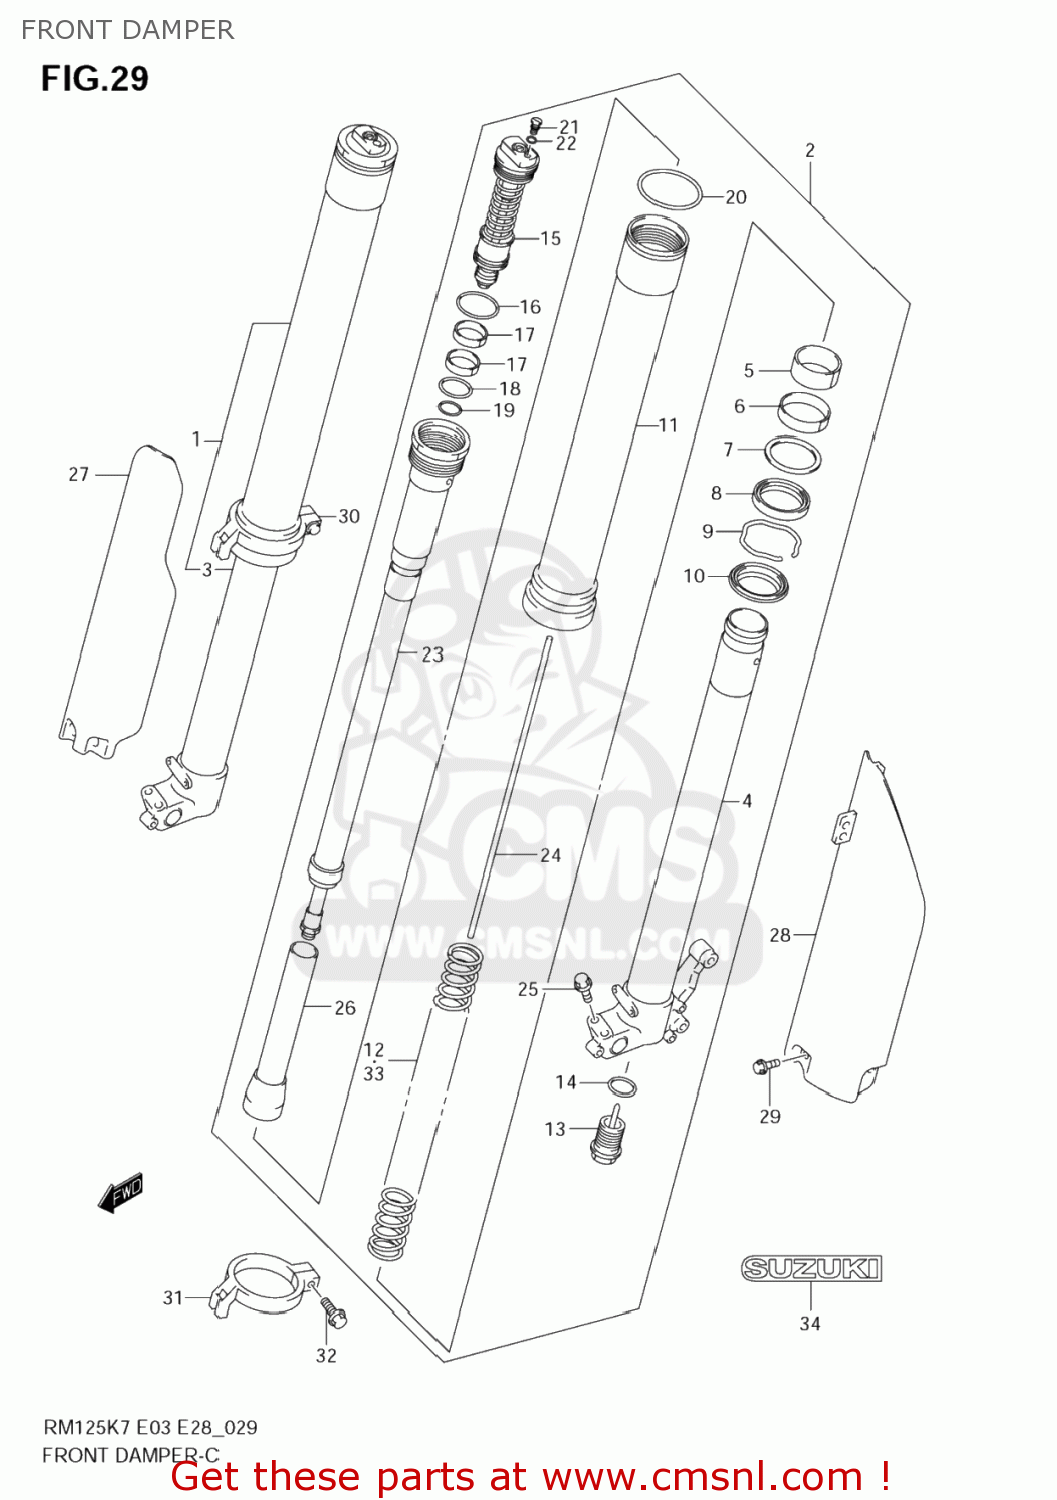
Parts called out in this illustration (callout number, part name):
1	DAMPER ASSY,FR FORK,R
2	DAMPER ASSY,FR FORK,L
3	TUBE,INNER,R
4	TUBE,INNER,L
5	BUSH,SLIDE
6	BUSH,GUIDE
7	SPACER,SEAL
8	SEAL,OIL
9	RING,OIL SEAL STOPPER
10	SEAL,DUST
11	TUBE,OUTER
12	SPRING,FR(SOFT,K=0.42)
13	BOLT,CTR
14	O RING
15	BOLT,FORK
16	O RING
17	BUSH,FORK BOLT SLIDE
18	O RING
19	O RING
20	O RING
21	BOLT,PLUG
22	O RING,PLUG
23	ROD,DAMPER
24	ROD,PUSH
25	BOLT
26	COLLAR,SPRING
27	PROTECTOR,FR FORK,R
28	PROTECTOR,FR FORK,L
29	BOLT(6X10)
30	GUIDE,PROTECTOR,R
31	GUIDE,PROTECTOR,L
32	BOLT
33	SPRING,FR(K=0.44)
34	EMBLEM,SUZUKI
